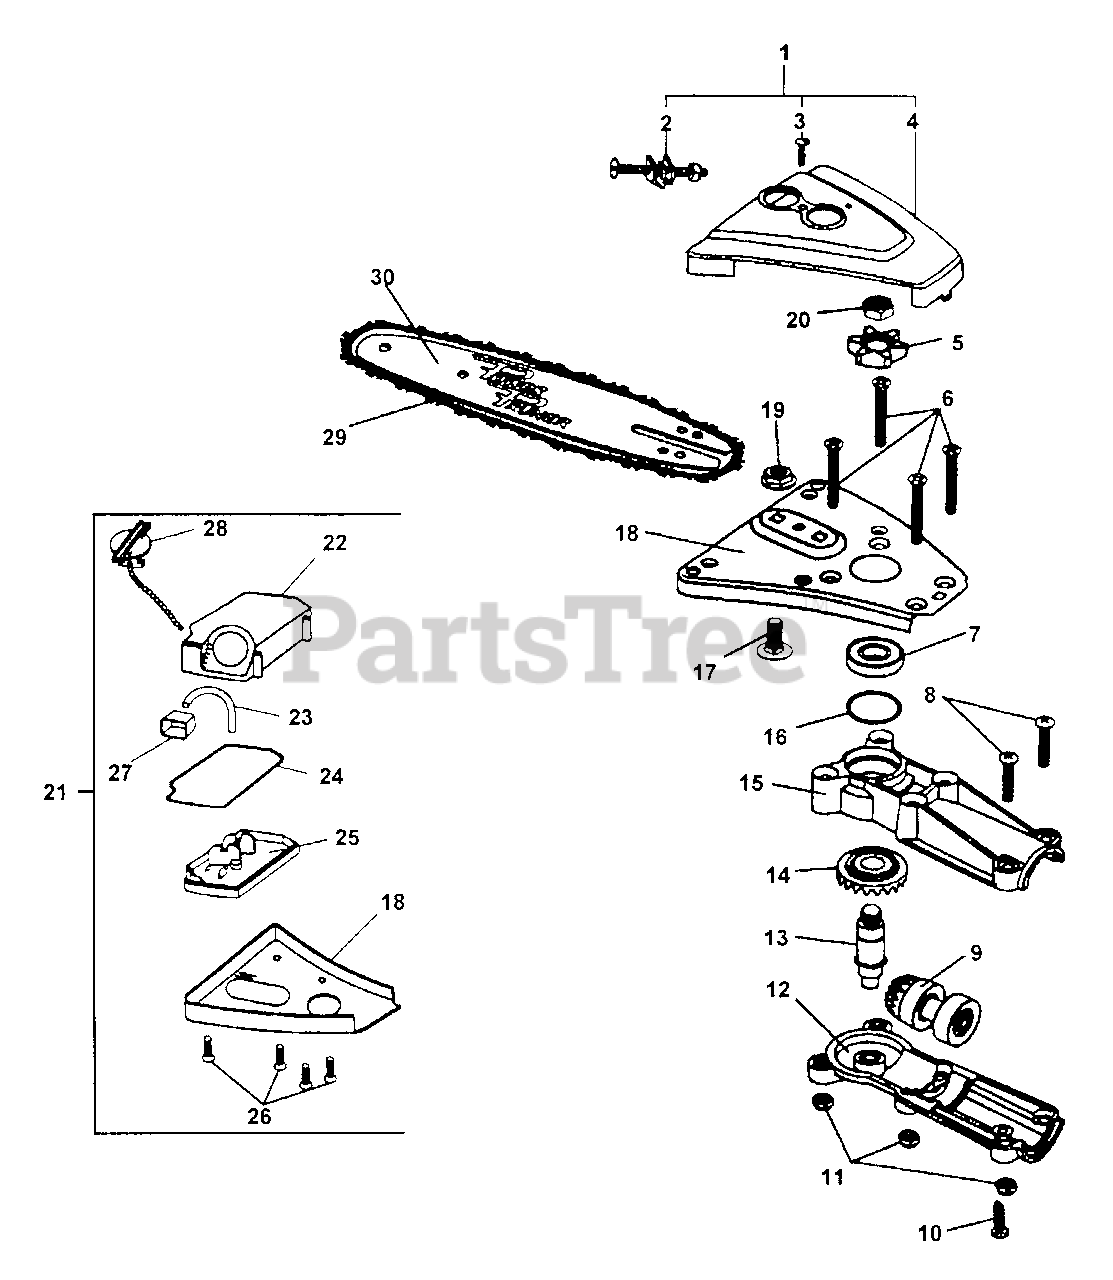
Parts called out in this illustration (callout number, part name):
1	SPROCKET COVER ASSY
2	TENSIONER KIT
3	SCREW - 8-32×1" - TORX PAN HEAD
4	GUARD, SPROCKET
5	SPROCKET
6	SCREW - TORX FLAT HEAD
7	BEARING, BALL 6001 DDU
8	SCREW, TORX 10-24 UNC 1-1/4
9	SHAFT, GEAR
10	SCREW - TORX PAN HEAD
11	NUT, LOCK 10-24 UNC
12	CASE, GEAR - RIGHT
13	SHAFT, GEAR
14	GEAR, BEVEL
15	CASE, GEAR - RIGHT
16	SHIM 0.004"
17	BOLT, CARRIAGE
18	SAW BAR CARRIER
19	NUT - FLANGE
20	NUT, HEX
21	SEMI-AUTO OILER ASSY
22	TANK, OIL
23	PIPE, FUEL 3x-5x-70 BLACK
25	TANK, OIL
26	SCREW, PH. F.H. M.S.
27	CUP, OIL
28	CAP, OIL
29	SAWING CHAIN - 90SG -- 10"
30	GUIDE BAR - 10" -- 90VS
